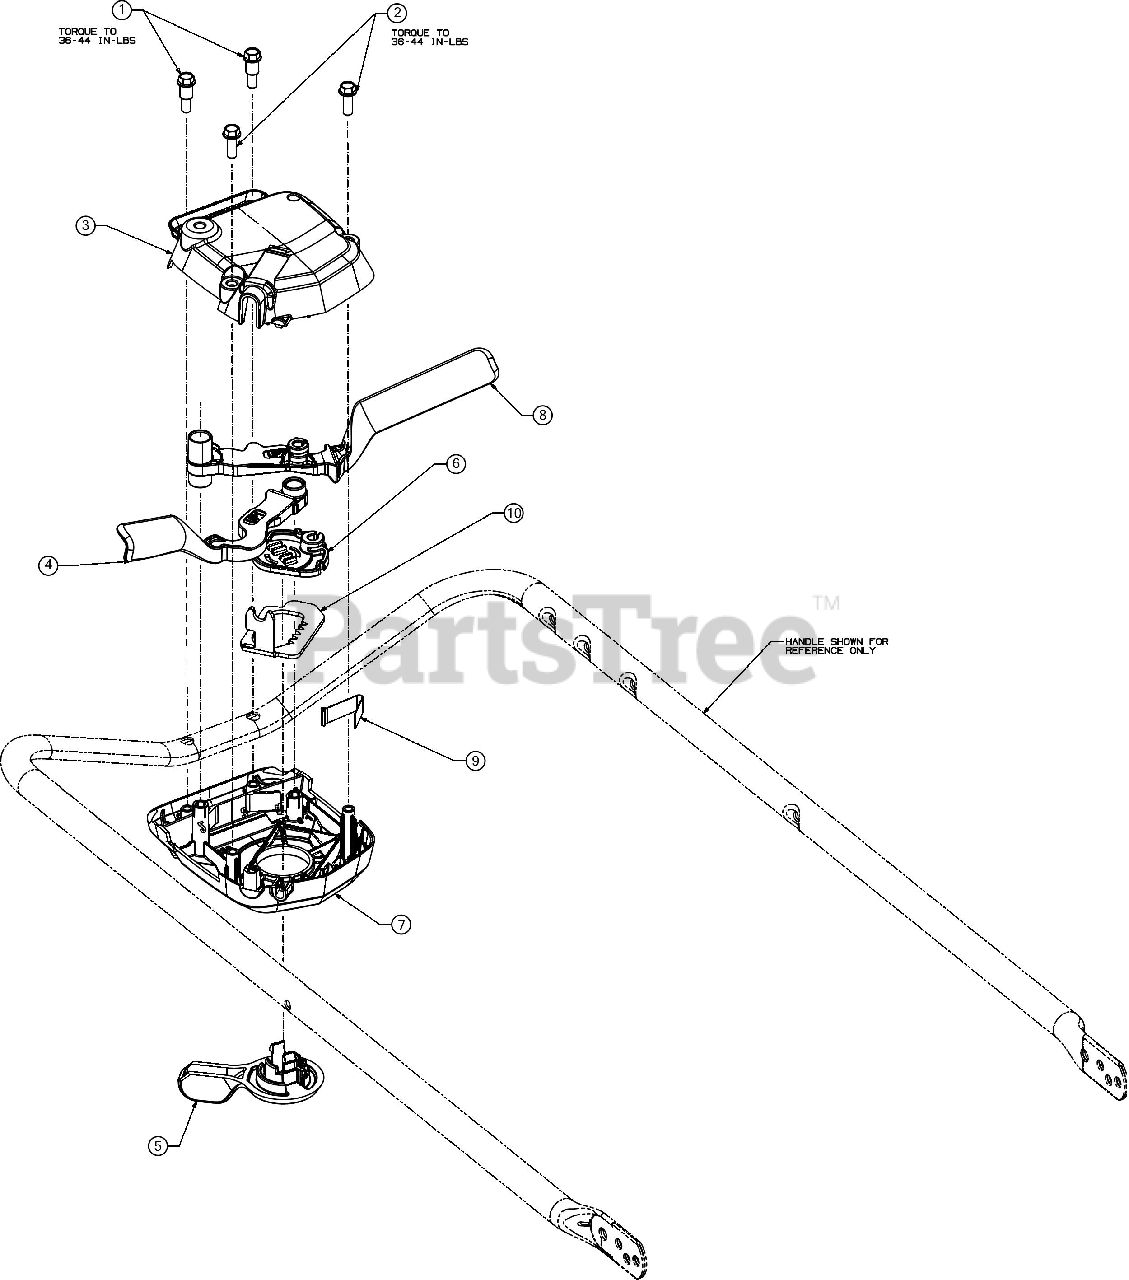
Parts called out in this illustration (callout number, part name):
1	SHOULDER SCREW 1/4-15 x .970
2	SCREW 1/4-15 x .750
3	LOWER CONTROL HOUSING
4	CONTROL LEVER (LH)
5	SPEED SELECT LEVER
6	CABLE SPEED ADJUST ACTUATOR
7	UPPER CONTROL HOUSING
8	CONTROL LEVER (RH)
9	SHIFT SPRING
10	RACK PLATE
